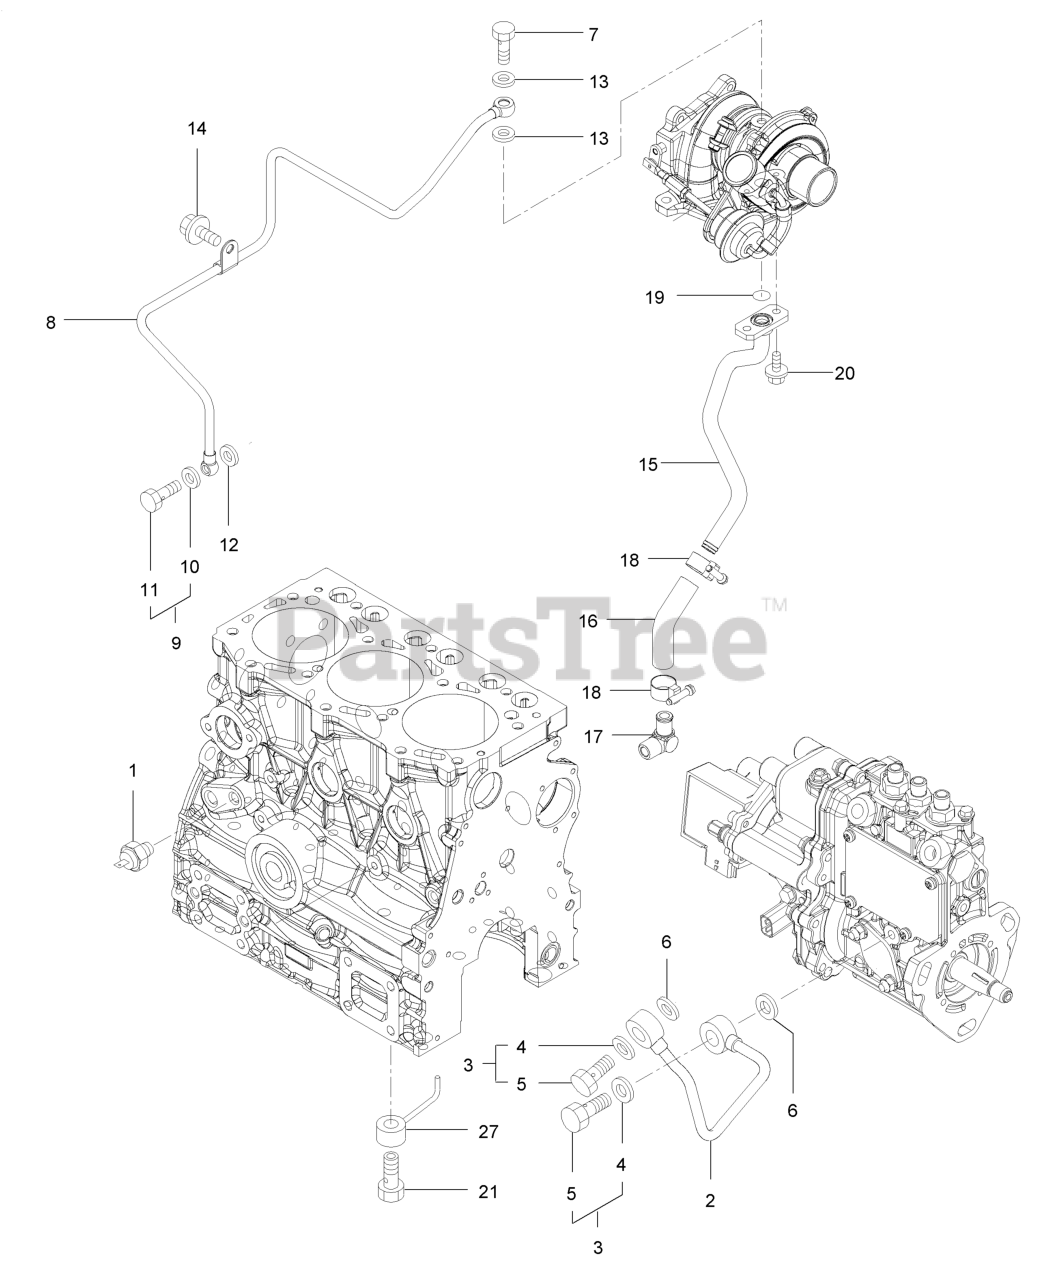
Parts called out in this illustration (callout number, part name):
1	Switch-Oil
2	Pipe-Oil
3	Joint Bolt ASM
4	Washer-Seal
5	Bolt-Joint
6	Washer-Seal
7	Bolt-Joint, Pipe
8	Pipe ASM-Lo
9	Joint Bolt ASM
10	Washer-Seal
11	Bolt-Joint
12	Washer-Seal
15	Pipe-Lo Return
18	Clamp-Hose
21	Valve ASM-Check
27	Nozzle ASM-Piston
